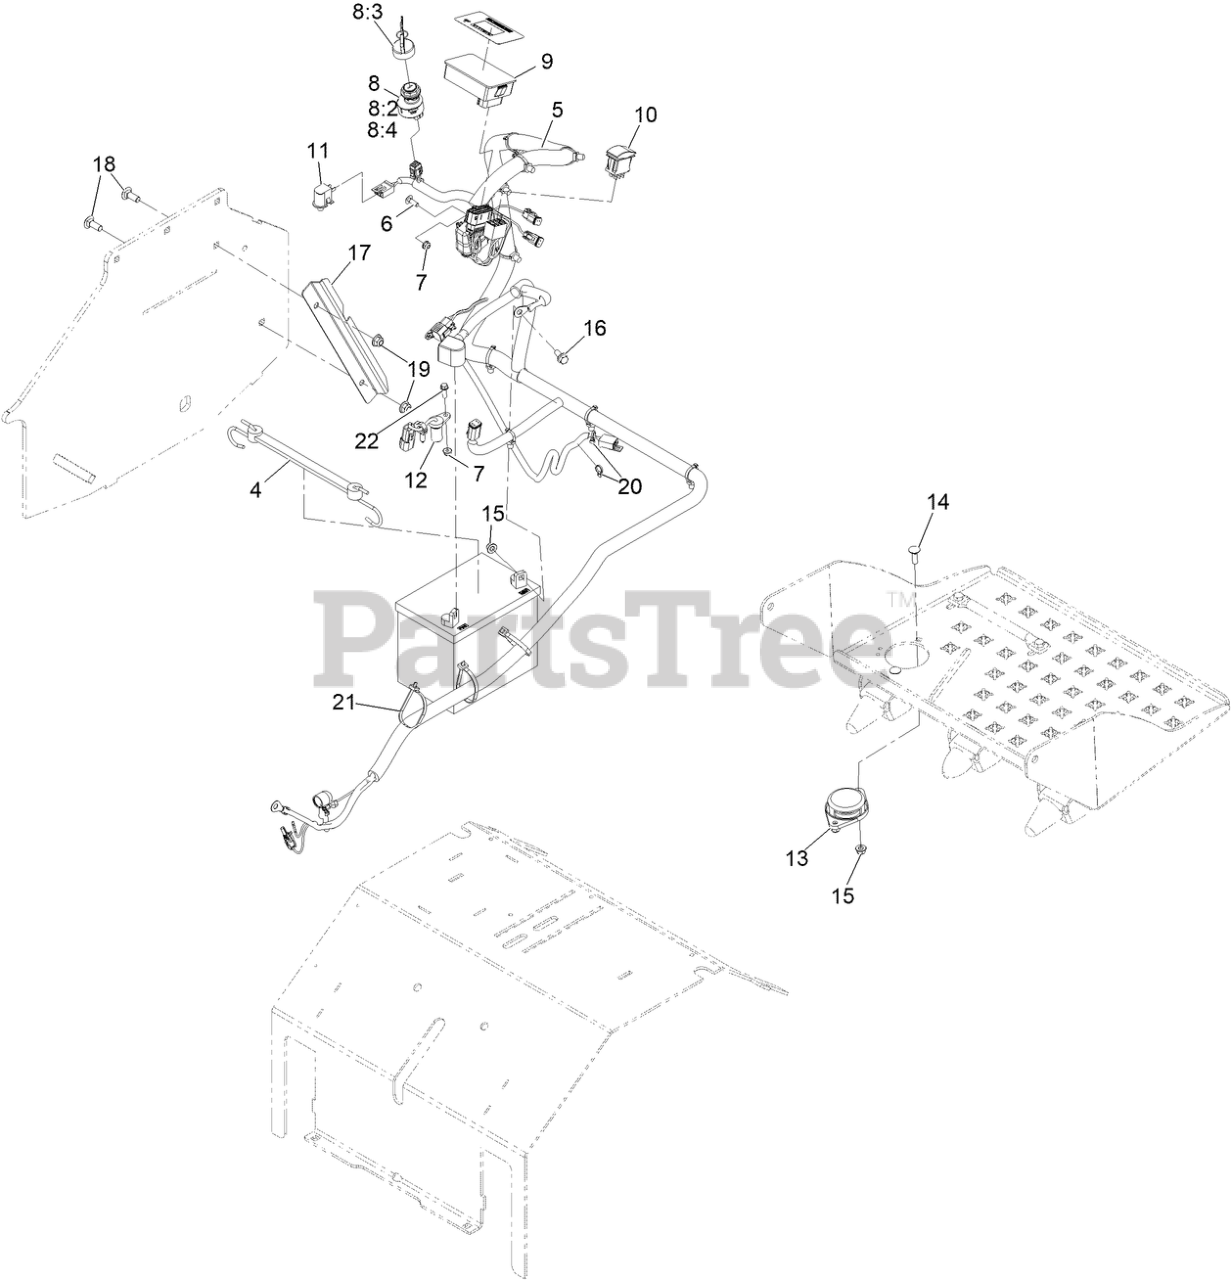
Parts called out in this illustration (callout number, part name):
4	HOLDDOWN-BATTERY
5	HARNESS-WIRE
6	BOLT-CARR
7	NUT-HF
8	IGNITION SWITCH ASM
8:2	NUT-MOUNTING
8:3	IGNITION KEY SET
8:4	WASHER-BACKUP
9	HOUR METER ASM
10	SWITCH
11	SWITCH-BAIL
12	SENSOR-QUADRATURE
13	SWITCH-SEAT
14	BOLT-CARR
15	NUT-HF, NI
16	SCREW-HHF
17	GUARD-HARNESS
18	BOLT-CARR
19	NUT-HF, NI
20	TIE-CABLE
21	TIE-CABLE
22	SCREW-HWH
